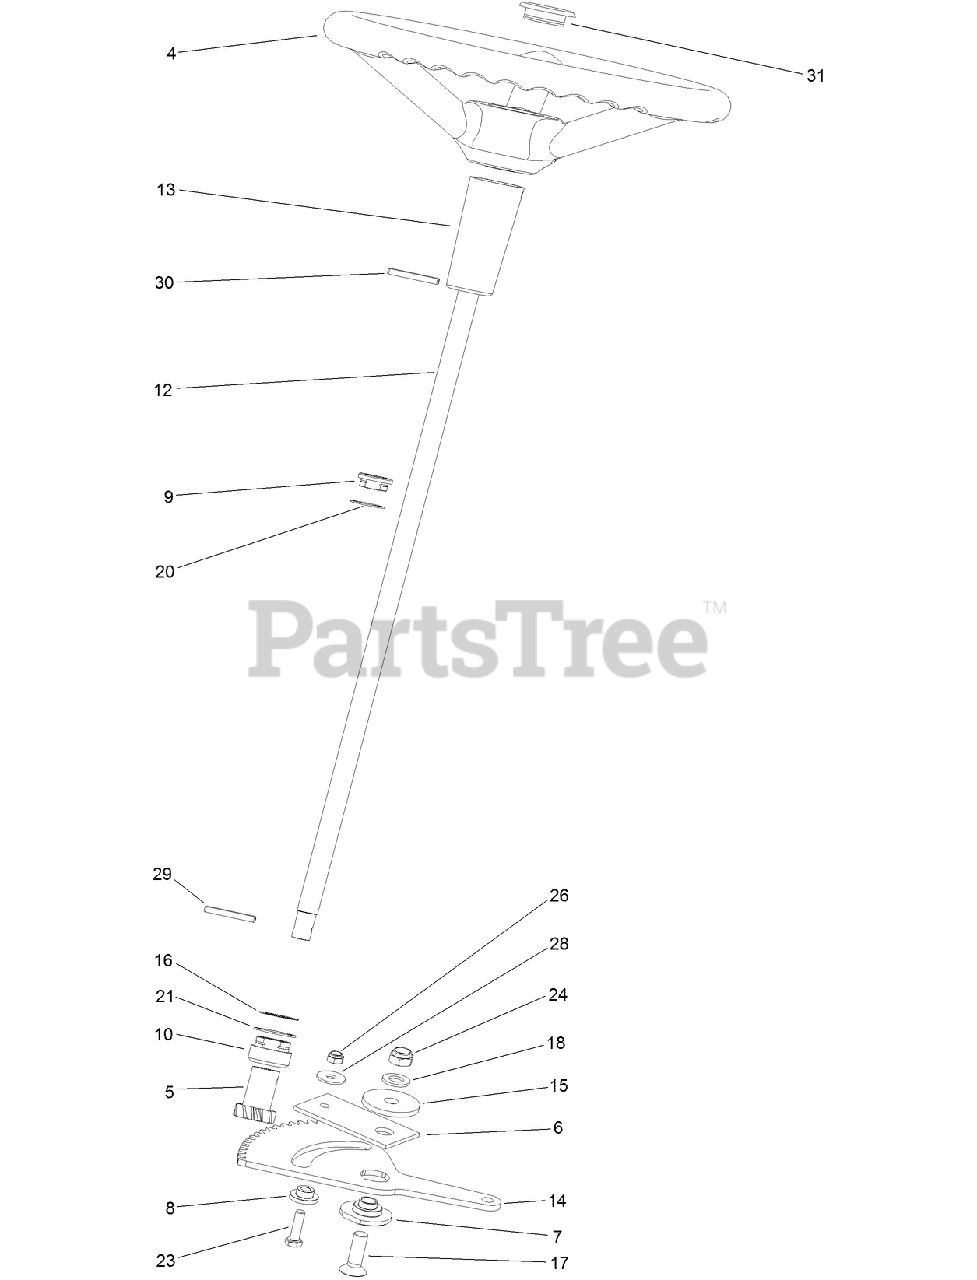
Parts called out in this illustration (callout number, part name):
4	WHEEL-STEERING
5	PINION-STEERING
6	PLATE-STEERING
7	PIVOT-STEERING
8	BUSHING-SECTOR
9	BEARING
10	BUSHING-PINION
12	SHAFT-STEERING
14	GEAR-SECTOR
15	WASHER
16	WASHER
18	WASHER-FLAT
20	RING-LOCKING
21	RING-LOCKING
23	SCREW-HH
24	NUT-HEX
26	NUT-LOCK, NI
28	WASHER-PLAIN
29	PIN-SPIRAL
30	PIN-SPIROL
31	CAP-WHEEL, STEERING
